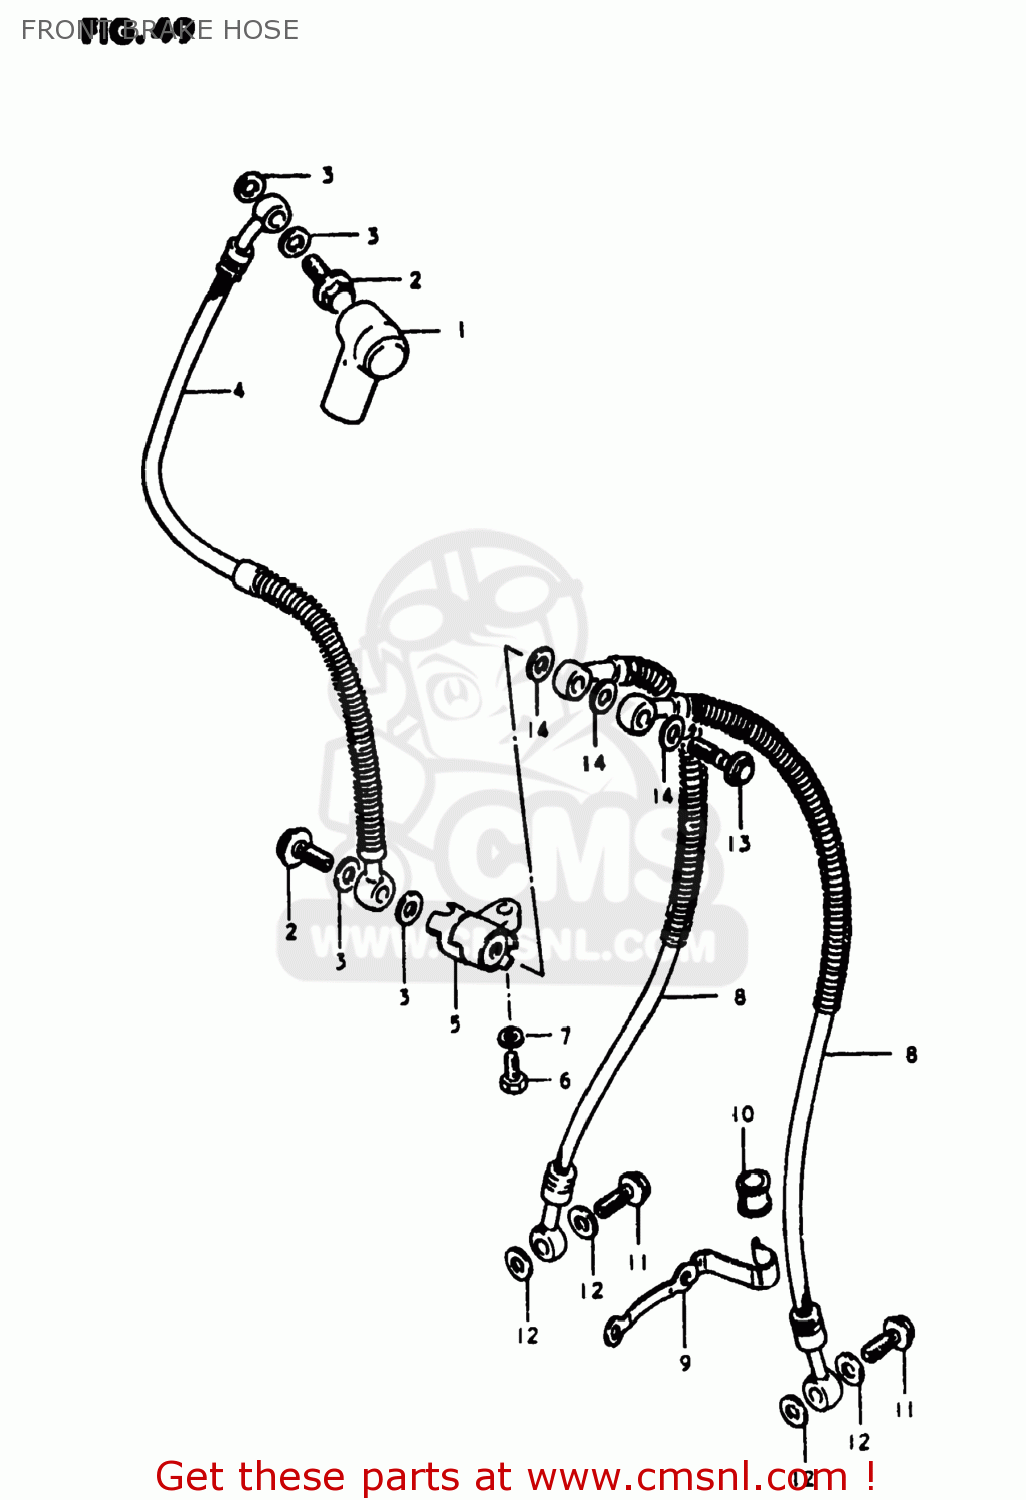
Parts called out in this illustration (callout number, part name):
1	BOOT,MASTER CYLINDER
2	BOLT,UNION
3	WASHER
4	HOSE,FRONT BRAKE
5	JOINT,BRAKE HOSE
6	BOLT
7	LOCK WASHER
8	HOSE, BRAKE NO.2
9	GUIDE,BRAKE HOSE NO.2
10	BUSH,BRAKE HOSE GUIDE,NO.2
11	BOLT,UNION
12	WASHER
13	BOLT,UNION
14	WASHER
